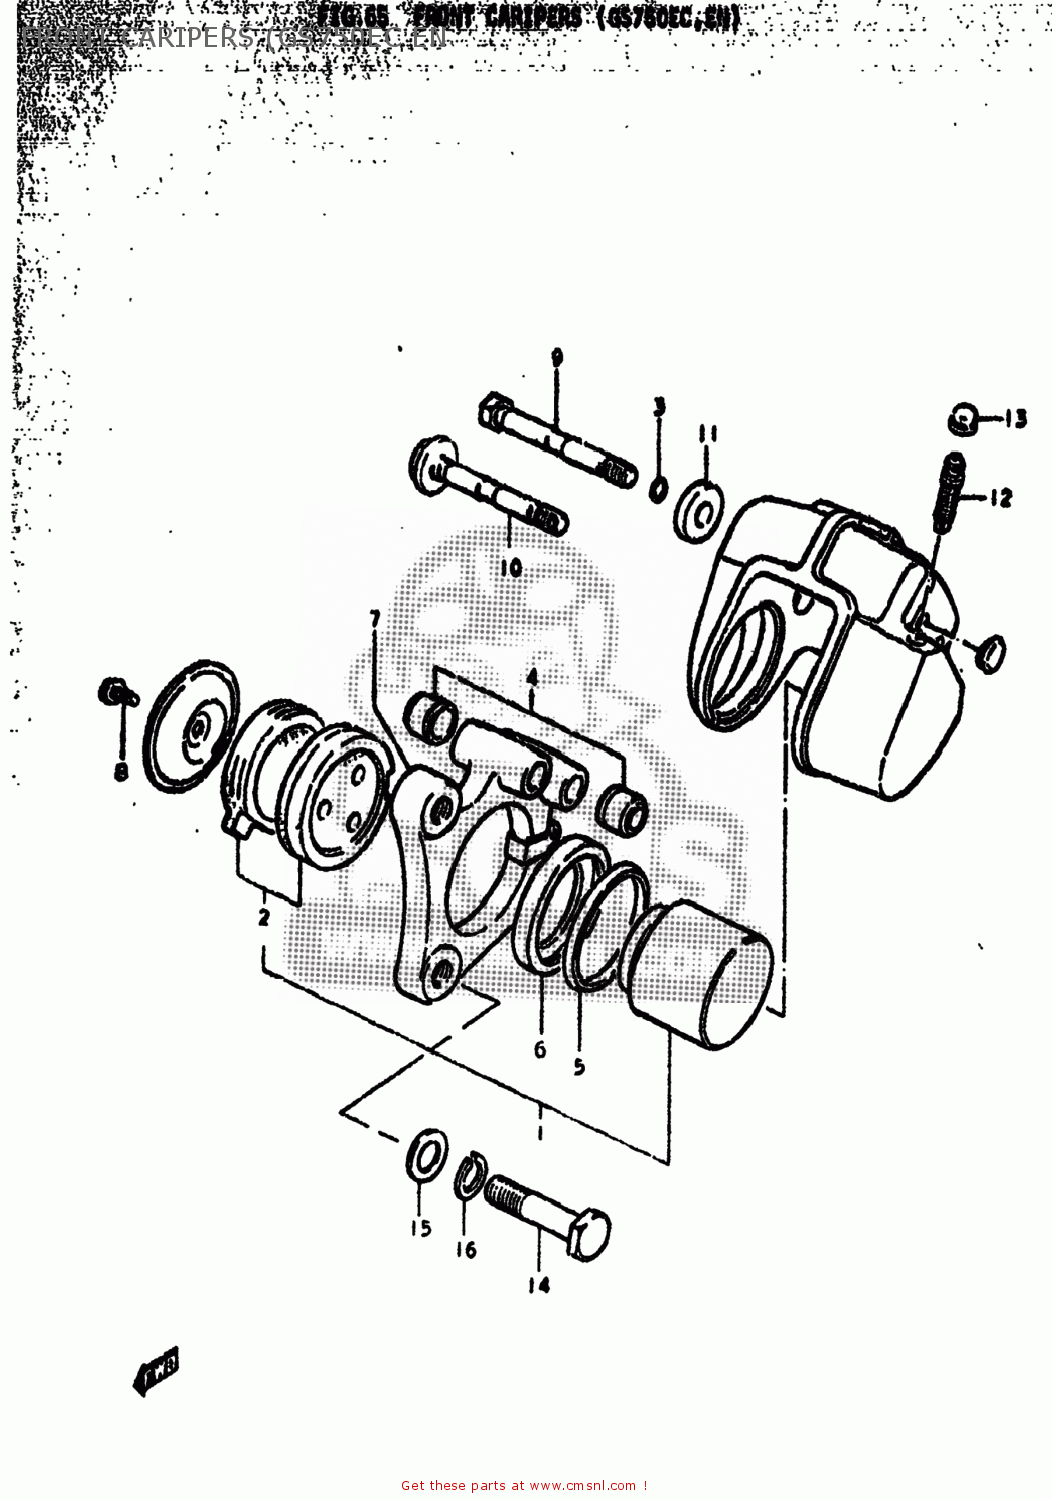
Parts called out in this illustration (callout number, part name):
0	CALIPER ASSEMBLY,FRONT,LEFT
1	PISTON/PAD SET,CALIPER
2	59302-45830 (MCA)
3	O RING
4	COVER,AXLE DUST
5	SEAL,PISTON
6	BOOT,PISTON
7	HOLDER, CARIPERS RH
8	SCREW 6X12
9	AXLE,CALIPER
10	AXLE,CALIPER
11	WASHER,AXLE
12	BLEEDER
13	CAP,BREATHER
14	BOLT
15	WASHER
16	LOCK WASHER
